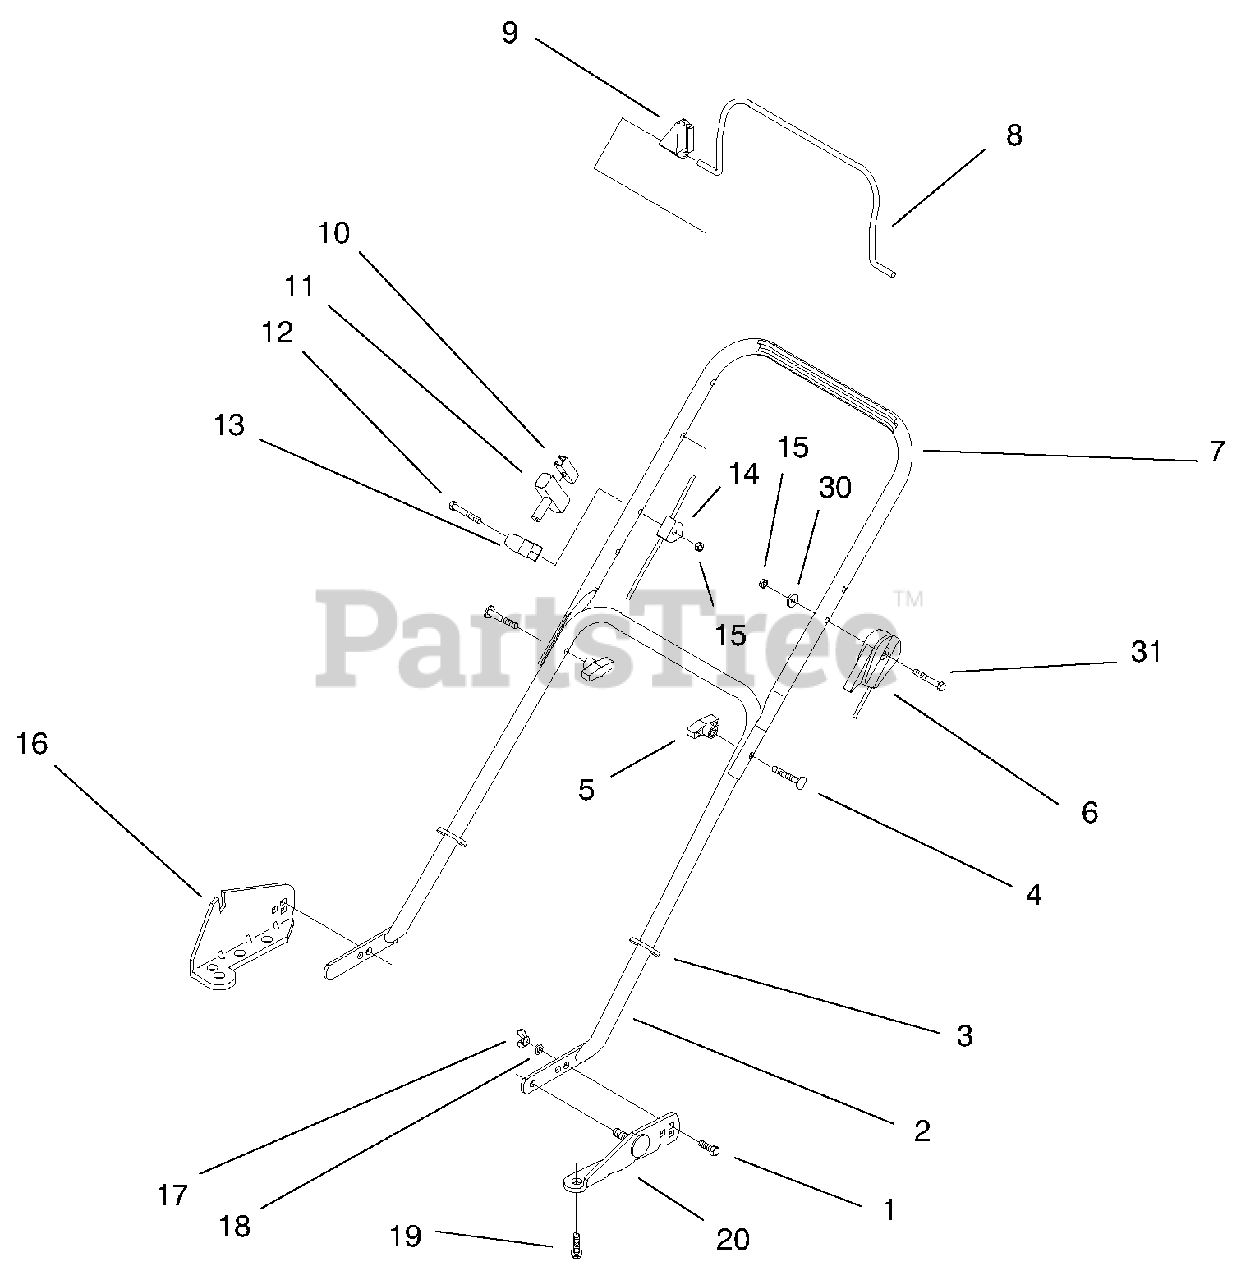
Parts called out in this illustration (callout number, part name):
1	Bolt-CARR
2	Handle Section-Lower
3	Tie Strap
4	Screw-Handle
6	Cable-Throttle
7	Handle Section-Upper
8	Bail-Flywheel Brake
9	Stop-Pivot
10	Clip-Rope
11	Handle-Starter
12	Screw-HH
13	Guide-Rope
14	Cable-Flywheel Brake
15	Nut-Lock
16	ASM-Bracket & Pin
18	Washer-Lock
20	ASM-Bracket & Pin
30	Washer
31	Screw-HH
